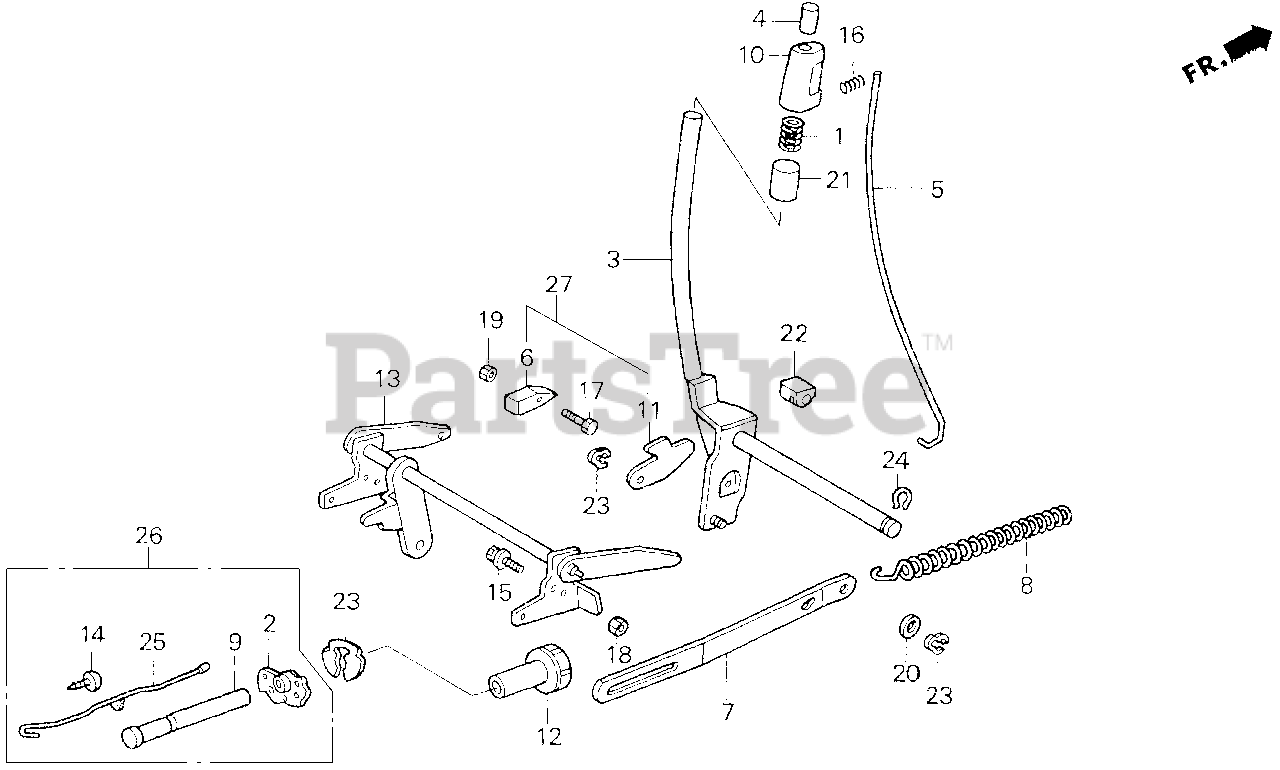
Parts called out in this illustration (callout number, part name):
1	SPRING, PUSH ROD
2	HEIGHT ADJUST SET
3	LEVER, HEIGHT ADJUST
4	KNOB, PUSH ROD
6	SPINDLE SET
7	PLATE, LIFT
8	SPRING, DECK LIFT
9	HEIGHT ADJUST SET
10	GRIP, HEIGHT ADJUST LEVER
11	SPINDLE SET
12	GRIP, HEIGHT CONTROL
13	LINK, CUTTER DECK LIFT
14	HEIGHT ADJUST SET
15	BOLT, CARRIAGE (8X16)
16	SCREW, SET (1/4")
17	BOLT, HEX. (6X25)
18	NUT, FLANGE (8MM)
19	NUT, SELF-LOCK (6MM)
20	WASHER, HEIGHT ADJUST
21	RETAINER, SPRING
22	BEARING, HEIGHT ADJUST
23	RING, HEIGHT ADJUST PIN
24	RING, SNAP (OUTER)
25	HEIGHT ADJUST SET
26	HEIGHT ADJUST SET
27	SPINDLE SET
